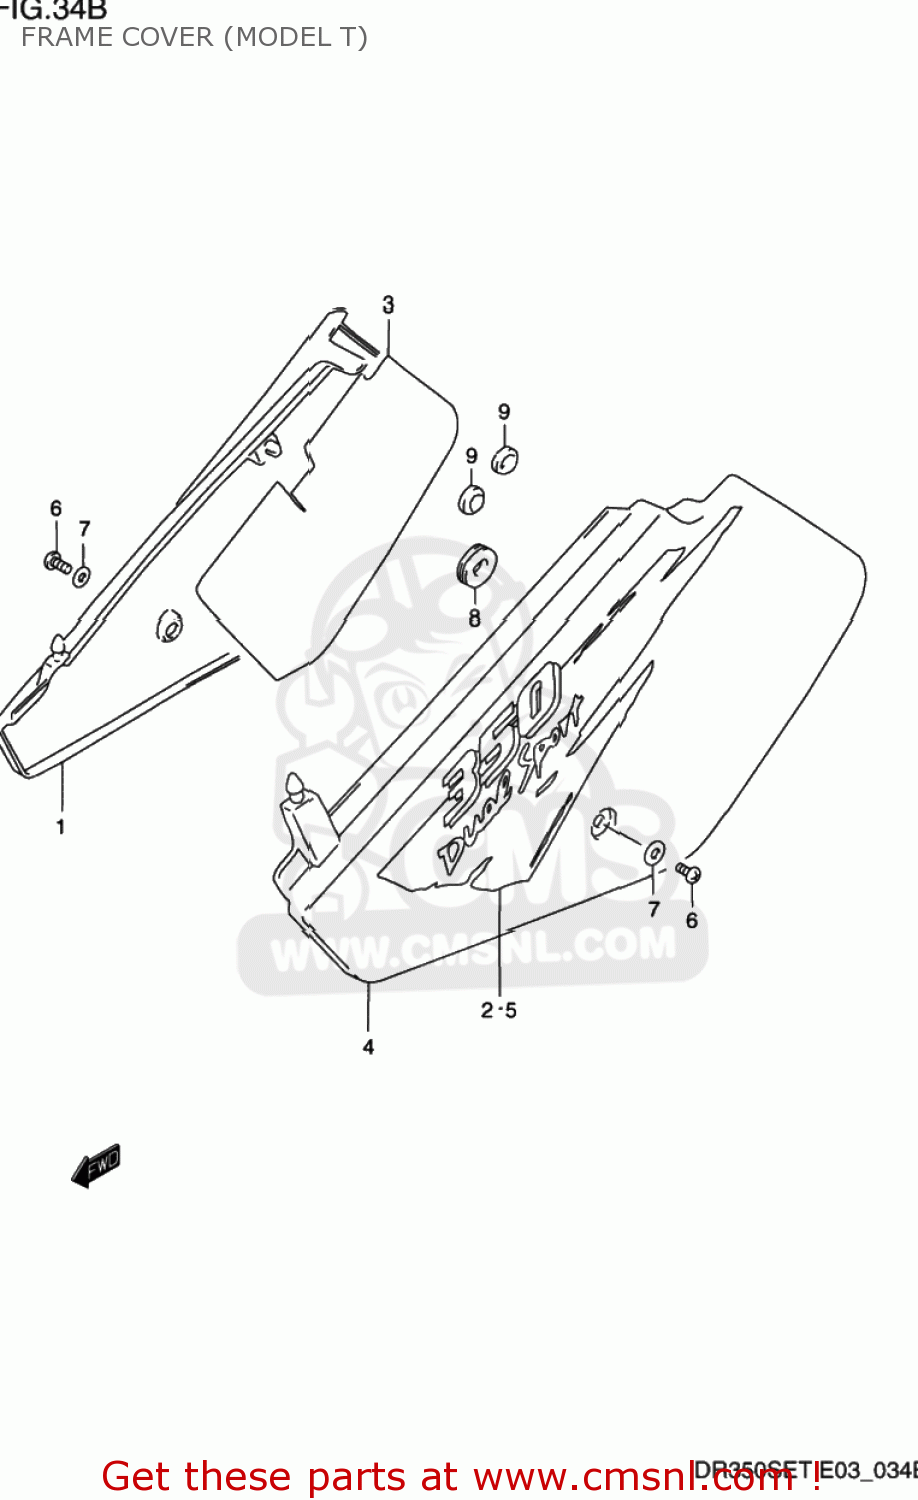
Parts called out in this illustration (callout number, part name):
1	COVER,FRAME,R(WHITE)
2	EMBLEM, RH
3	SHIELD,FRAME COVER,R
4	COVER,FRAME,L(WHITE)
5	TAPE,FRAME COVER,LEFT
6	SCREW
7	WASHER
8	CUSHION
9	CUSHION
